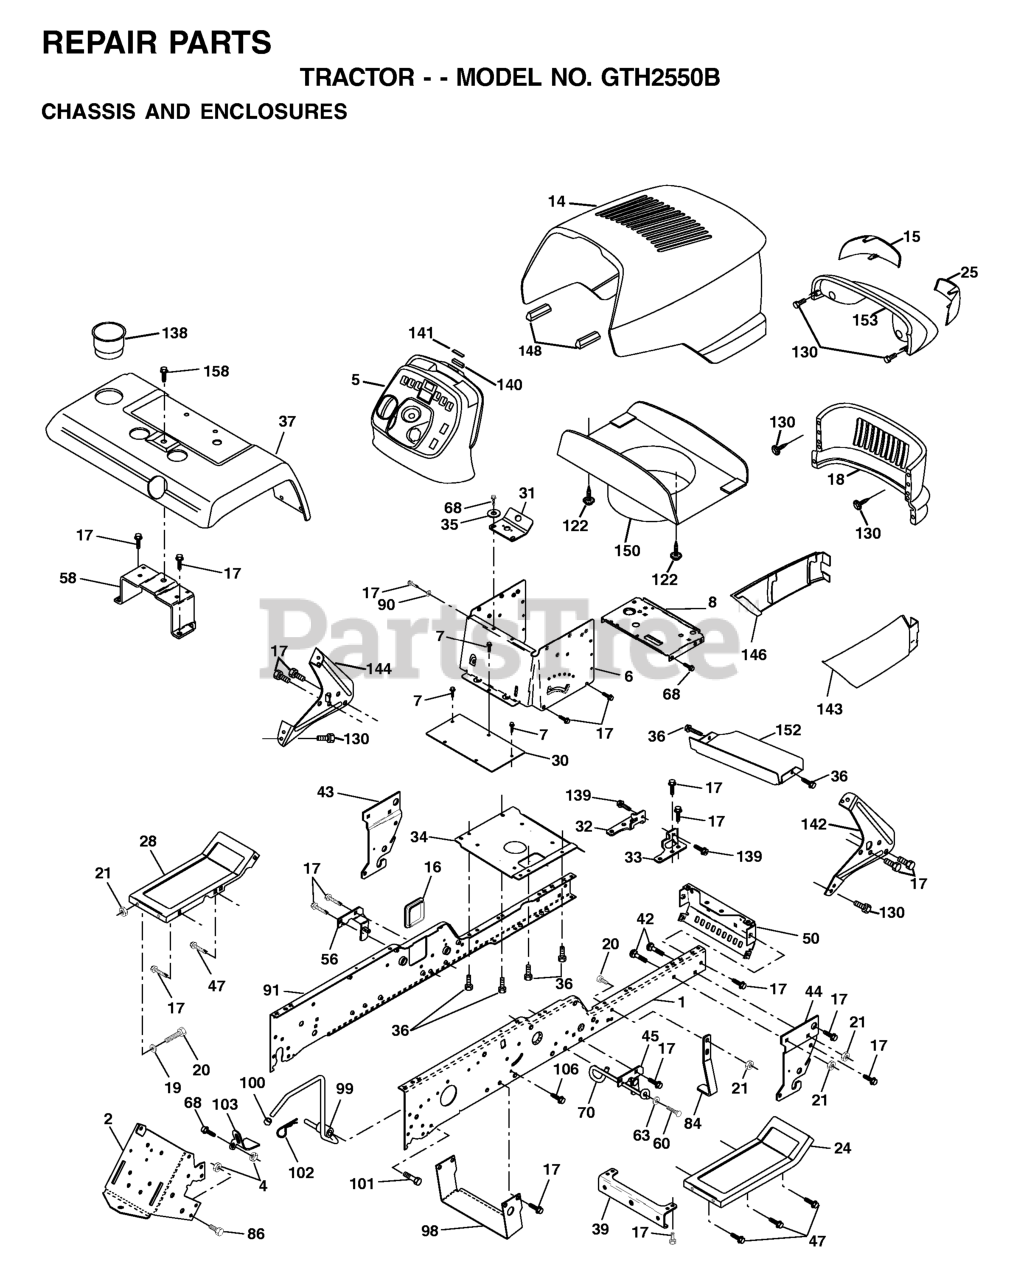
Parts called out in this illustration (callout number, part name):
2	DRAWBAR, GT
4	Nut, Lock Hex 7/16 Unc
5	DASH.STEALTH.YTGT.2CYL.BLK
6	DASH VGT, LOWER
7	SCREW
8	SUPPORT, BATTERY
14	HOOD ASM.
15	LENS LH
16	COVER ACCESS
17	SCREW 3/8-16X3/4
18	GRILLE
19	WASHER
20	BOLT
24	FOOTREST RH
25	LENS RH
28	FOOT REST LH
30	SADDLE.HYDRO.95
31	BRACKET SUPT 1-PC VGT STEERING
34	PLATE ASM ENG CHASSIS
35	WASHER
36	SCREW 5/16"
39	BRACKET AXLE, FRONT
42	BOLT D
43	FRONT SUSPENSION BRKT LH
44	FRONT SUSPENSION BRKT RH
45	BRACKET SUSP RH
50	BRACKET, CHASSIS FRONT
56	BRACKET ASM, SUSP CHASSIS
58	BRACKET ASM, FENDER
60	SCREW.3/8-16
63	WASHER
68	Screw 5/16-18 x 1/2 Hex, Self Tapping 5/16-18 x 1/2
84	MOWER STOP
86	BOLT
90	LOCKWASHER
99	ROD ASMBLY BYPASS
100	PLUNGER CAP
101	SCREW LT
102	RETAINER M
103	BRACKET LOCK BYPASS
106	SCREW
122	SCREW.HEX.WS.HD.8-18 X 7/8
130	SCREW
139	BOLT, SHOULDER 5/16-18
140	MAGNET STEALTH
141	STRIKER PLATE
142	BRACKET DASH STEALTH(R)
143	SKIRT GRILLE RH
144	BRACKET DASH STEALTH LH
146	SKIRT GRILLE LH
148	EXTRUSION BUMPER (3 2) (2 2)
150	DUCT HEAT HOOD
152	BROWNING SHIELD
158	SCREW 3/8-16X1/2
